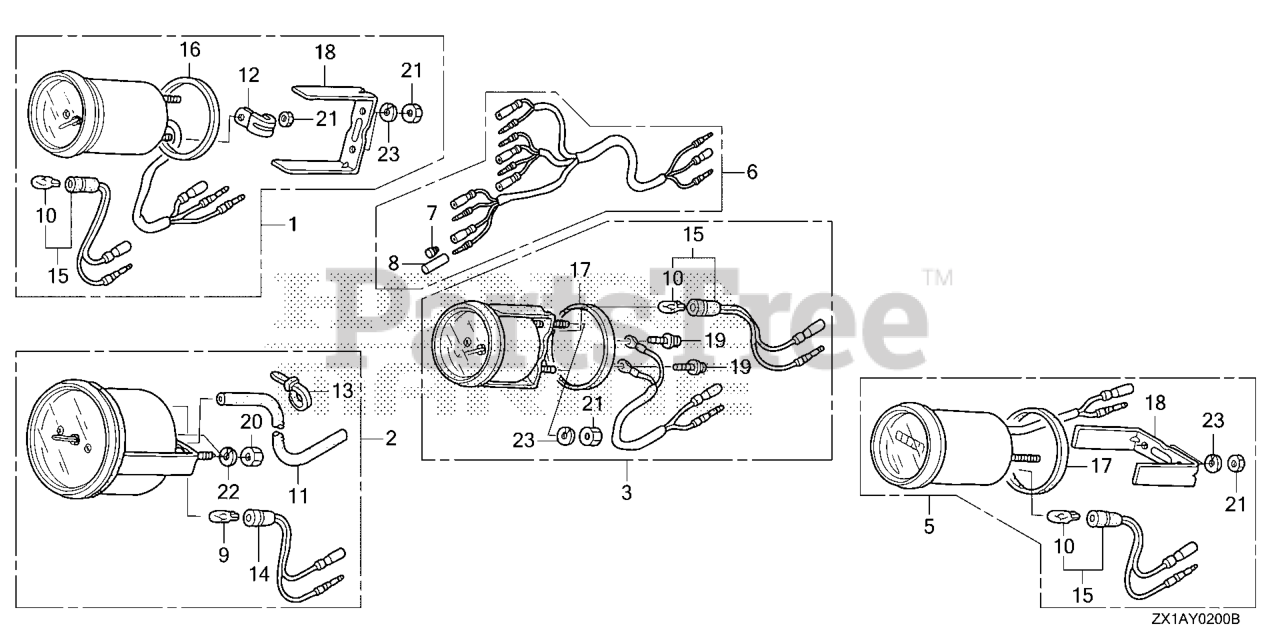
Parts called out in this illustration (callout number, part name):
1	METER KIT, TRIM (WHITE)
1	METER KIT, TRIM (B) (BLACK)
2	SPEEDOMETER KIT (WHITE)
2	SPEEDOMETER KIT *NHA85* (B) (BLACK)
3	METER KIT, VOLT (WHITE)
3	METER KIT, VOLT *NHA85* (B) (BLACK)
4	METER KIT, TACHO
4	METER KIT, TACHO (B)
5	METER KIT, HOUR (WHITE) (NA USE ALT:39700-ZW5-000ZA)
5	METER KIT, HOUR (B) (NA USE ALT:39700-ZW5-000ZA)
6	HARNESS ASSY., METER (B)
7	PLUG, CONNECTOR (INNER) (TROLLING CONTROL)
8	PLUG, CONNECTOR (OUTER) (ENGINE NO.)
9	BULB, WEDGE BASE (T10) (12V 1.7W) (STANLEY)
10	BULB, WEDGE BASE (12V1.7W) (TOSHIBA)
11	TUBE, SPEED METER (4X7X8000)
12	CLAMP
13	BAND, SELF-LOCK
15	SOCKET
16	GASKET (TO 1015209) (FROM 1015210)
17	GASKET
18	BRACKET (TO 1015209) (FROM 1015210)
19	SCREW-WASHER (3X22)
21	NUT, HEX. (4MM)
23	WASHER, SPRING (4MM)
